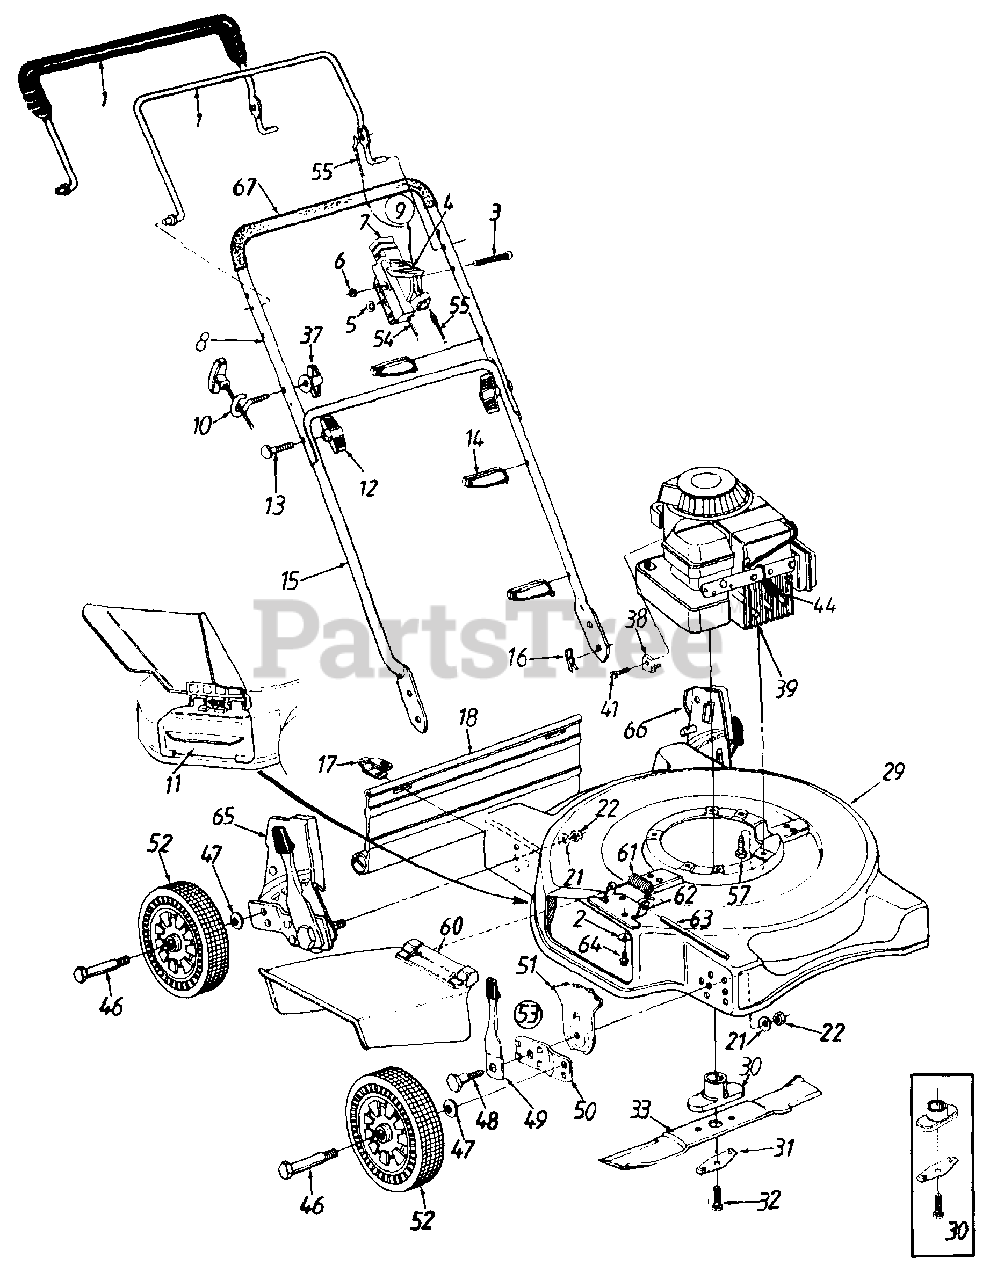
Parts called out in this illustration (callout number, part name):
2	Bell Washer
3	Oval C-Sunk Mach. Scr.
4	Throttle Lever
5	Spring Washer
6	Hex Lock Nut
7	Throttle Housing
10	Rope Guide
11	Mulch Plug
12	Hand Knob
13	Curved Hd. Bolt 5/16-18 x 2"
14	Cable Tie
16	Hairpin Clip
17	Hinge Clip
18	Rear Flap: 20"
21	Bell Washer
22	Hex Nut 3/8-16 Thd.
31	Blade Bell Support
32	Hex Bolt 3/8-24 x 1.5"
33	Cutting Blade: 20"
37	Wing Nut
38	Cable Clamp (B&S)
39	Engine
41	Hex Wash. Hd. TT Screw #10-32 x .62" Lg. (B&S)
44	Spark Plug Boot
46	Axle Bolt
47	Bell Washer
48	Shoulder Bolt
49	Spring Lever Assembly w/Knob
51	Height adj. Plate
52	Wheel Assembly Complete
53	Height Adj. Assembly: RF
54	Throttle Cable: 51"
55	Control cable: 39"
57	Hex Lock Washer
60	Chute Deflector Assembly
61	Torsion Spring
62	Adapter Plate
63	Hinge Pin
64	Hex TT Screw
67	Foam Grip
